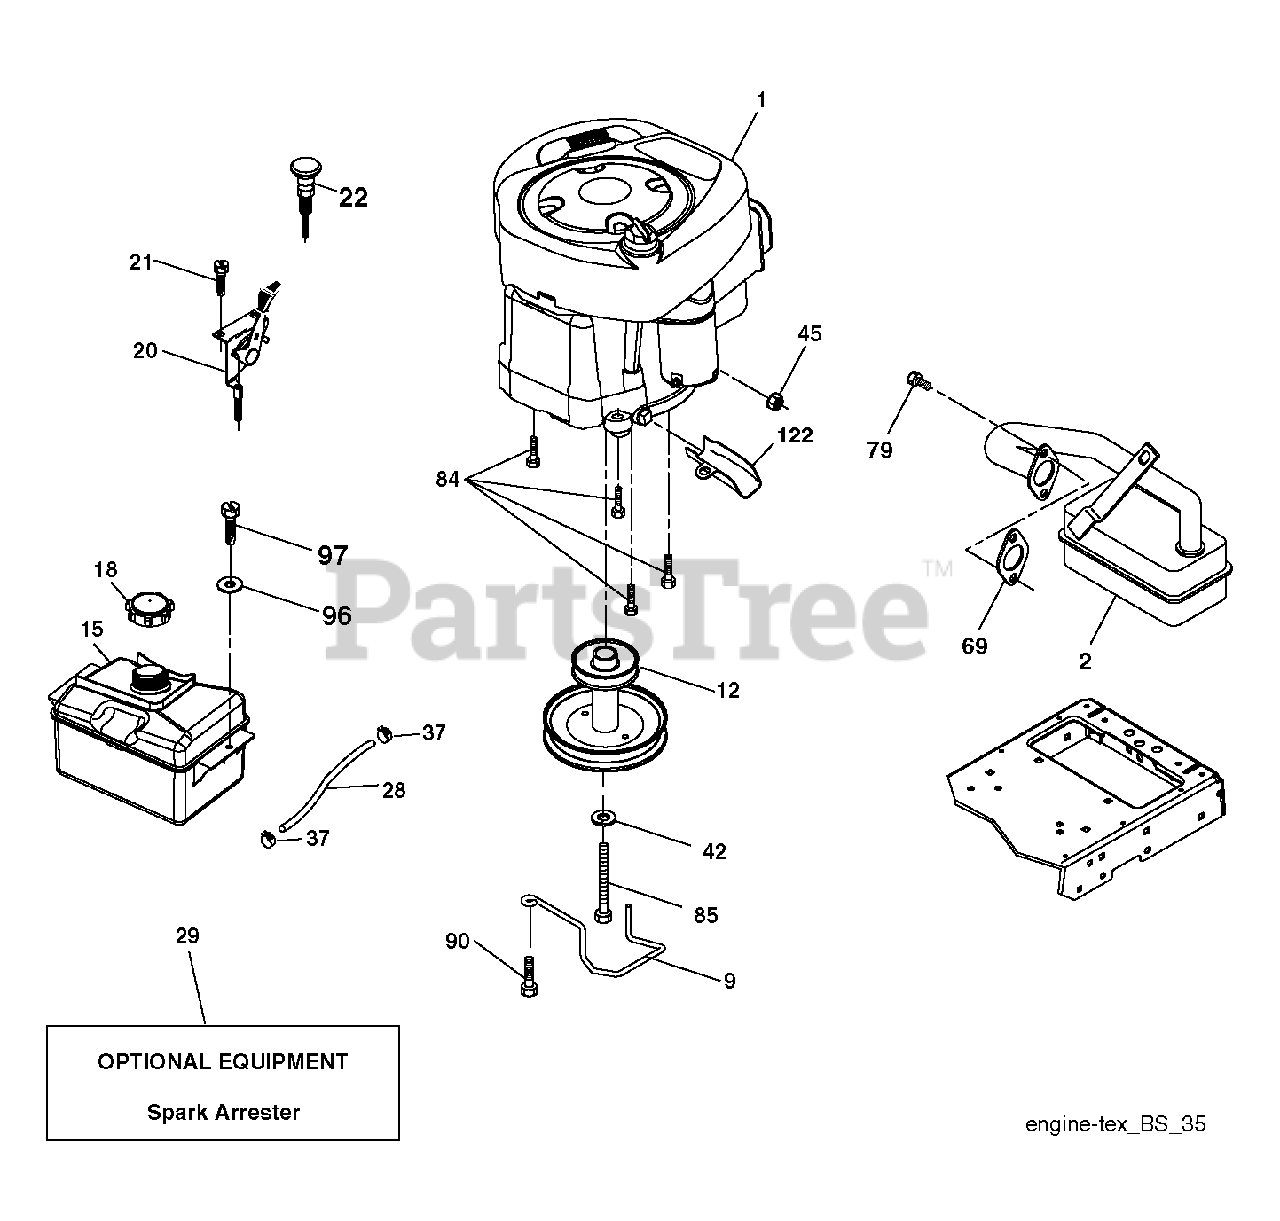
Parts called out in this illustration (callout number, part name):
9	KEEPER.BELT.ENGINE.4.2
12	PULLY ENGINE
15	TANK FUEL FRT 1.5 GAL
18	CAP ASM.FUEL.2.25"FR.
20	CONTROL.THCK.COBRA.BS
21	SCREW.#10 X 0.750.BOS THREAD
22	CONTROL.CHOKE.ERGO.1CYL.30".YE
29	ARRESTER SPARK (OPTIONAL)
42	LOCKWASHER
45	NUT
69	REPL BY 532 27 22-93
79	SCREW.SOCKET HD.5/16-1
85	BOLT HEX 7/16-20X4-1/4"
90	SCREW 3/8-16X1
97	SCREW HEXWSHR 1/4-20X3/4
122	EXTENSION DRAIN OIL
